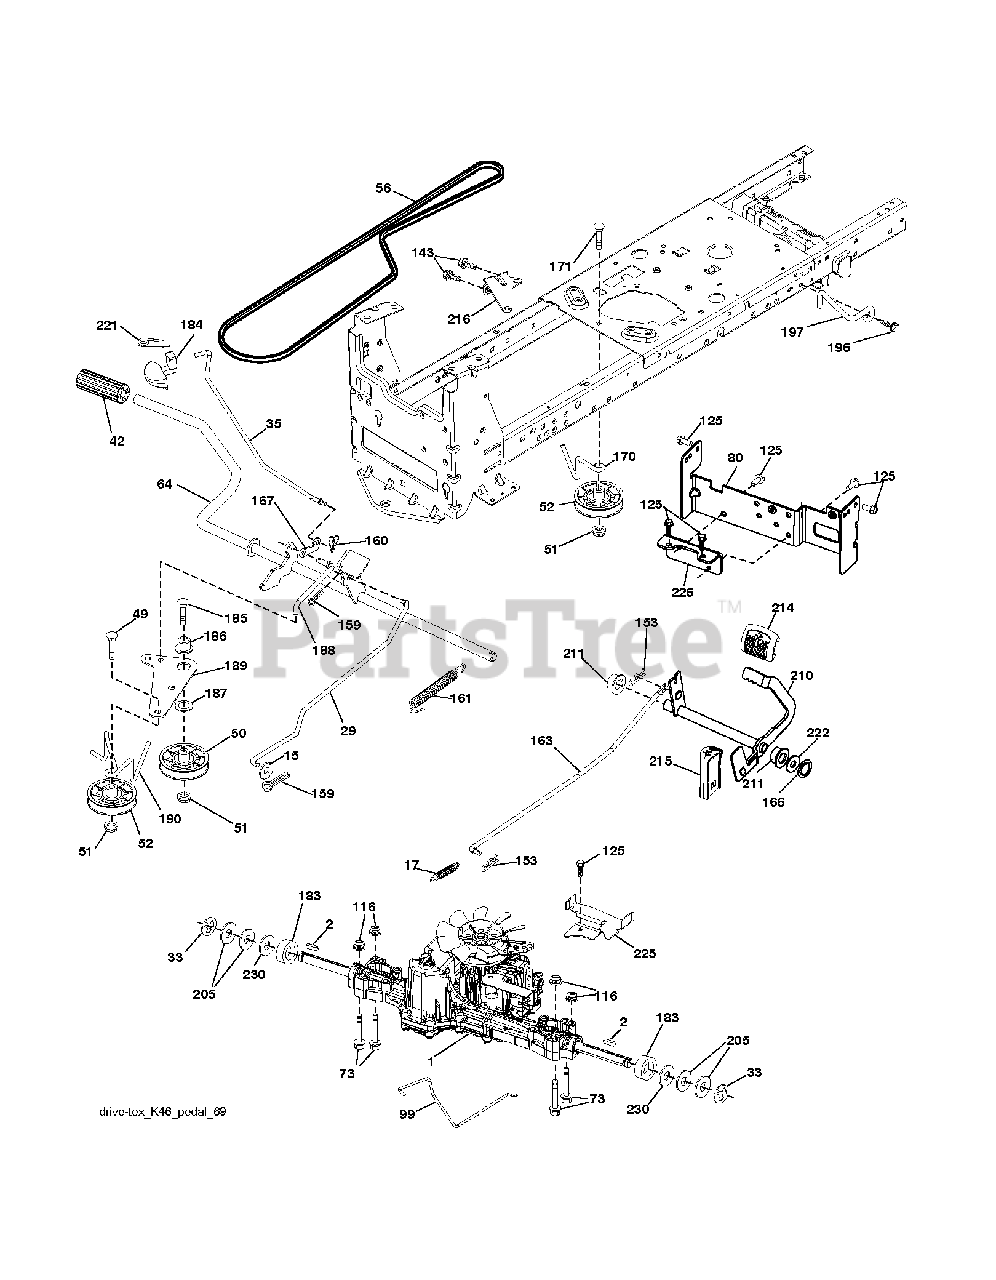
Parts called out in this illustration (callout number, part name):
2	SQUARE KEY
15	WASHER
17	SPRING.BRAKE.K46.GREEN
29	ROD.BRAKE.K46
35	ROD.CNTRL.PARK.PREDATOR.LT.TEX
42	PEDAL COVER T
50	IDLER.FLAT.910.OFFSET
51	NUT LOCK FLG 3/8-16 UNC
52	IDLER.V-GROOVE.910.OFFSET
56	V-BELT.MOWER.92.40.42/K46
64	SHAFT.ASM.PEDAL.BRK.CNTR
73	BOLT HEX 5/16-18 GR 5
80	STRAP.TORQUE.K46.K57R.TT
99	ROD.SPRING.BYPASS.K46.LT.Z
116	NUT LOCK HEX FLANGE 5/16-18
125	SCREW
143	SCREW LT
153	RETAINER M
159	COTTER PIN
160	RETAINER CLIP
161	SPRING, RETURN LT
163	ROD.CONTROL.PEDAL.K46
166	NUT.PUSH.625
167	LATCH.BRAKE.SPRING
170	KEEPER.V-IDLER.CENTER.
183	SPACER AXLE
184	HANDLE.PARKING.BRK.PRED.LT.RED
186	SPACER.RETAINER
187	WASHER 12/32X2X10GA
188	RP LINK.CLUTCH.GROUND.DRIVE
189	BELLCRANK.GROUND.DRIVE.TEX.
190	KEEPER.BELLCRANK.DRIVE
196	SCREW 3/8-16X1
197	LINK.CLUTCH.ANIT-ROTAT
210	ROCKER.ASM.PEDAL.CONTR
211	BEARING.NYLON
214	PEDAL.FORWARD.PAD.TEX
215	PEDAL.REVERSE.TEX.GT.4
216	BRACKET.PULLEY.IDLER.W/TEX
221	RETAINER.SPRING.CLIP.H
222	WASHER 21/32 X 1-1/4 X 10 GA.
225	KEEPER.BELT.TRANSAXLE.K46
226	BRACKET.MOUNT.TORQUE.K46.TLT
230	WASHER.HARDENED
